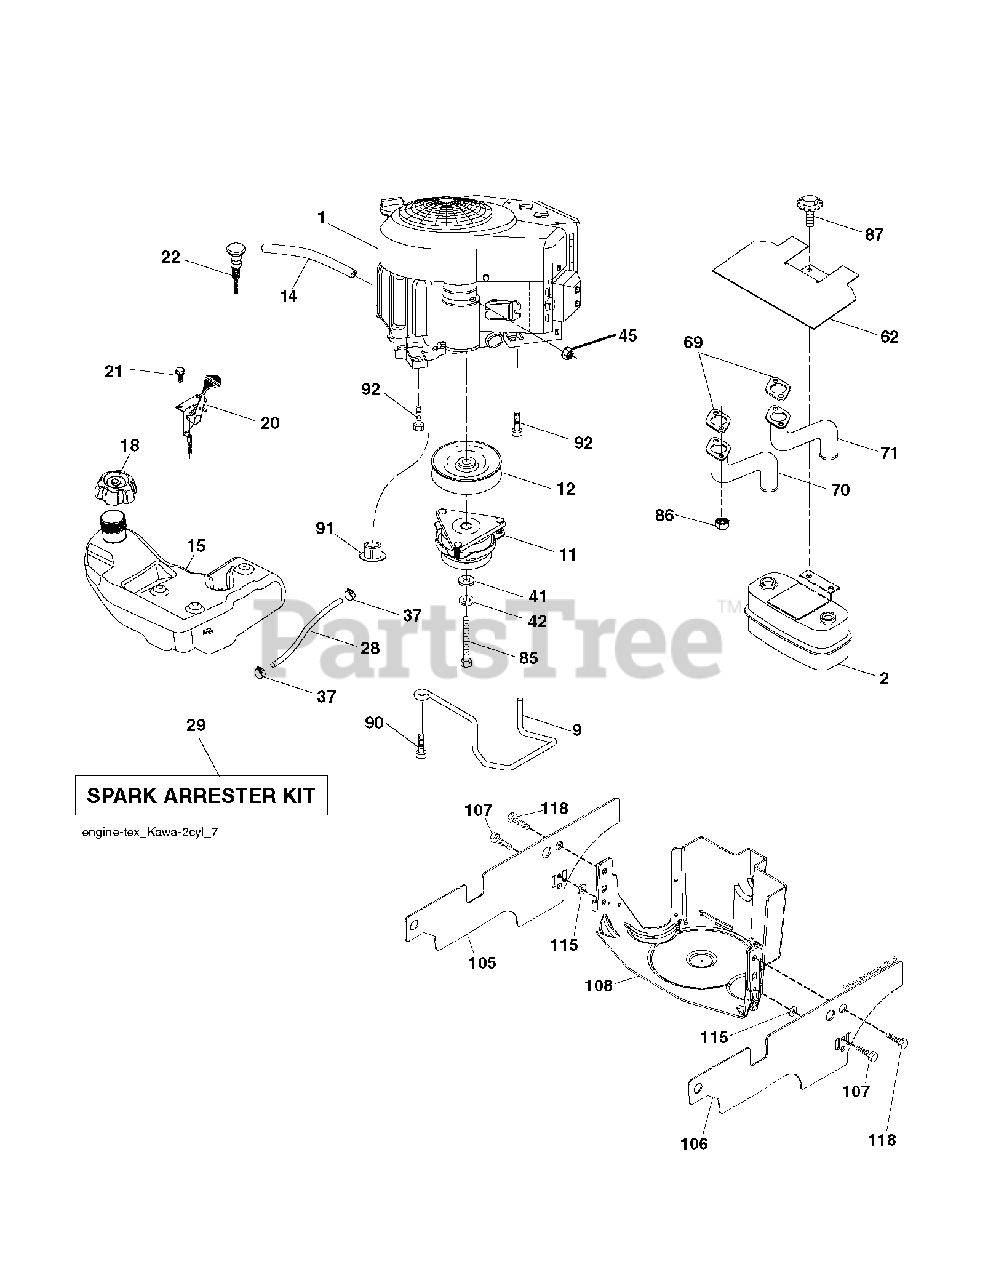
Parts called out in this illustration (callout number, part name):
1	Husqvarna TBD
2	MUFFLER.TWIN.CYL.LOW.TONE
9	KEEPER.BELT.ENGINE.4.2
11	CLUTCH.ELECTRIC.LT.48"*
12	PULLEY.ENGINE.TUFFTORQ
14	TUBE, DRAIN OIL ASM.
15	TANK.FUEL.4GAL
18	RP CAP FUEL
20	THROTTLE CABLE
21	SCREW.#10 X 0.750.BOS
22	CONTROL.CHOKE.ERGO.PUSH-IN.BLA
28	REPL BY 532 00 85-43
29	KIT.SPARK ARRESTOR 794945 B&S
37	HOSE CLAMP
42	LOCKWASHER
45	NUT
62	SHIELD.HEAT.MUFFLER
70	TUBE.EXHAUST.LH.FR961/FR730
71	TUBE.EXHAUST.RH.FR961/FR730
85	BOLT HEX 7/16-20X4-1/4"
86	NUT.HEX.FLANGE.TOPLOCK
87	Bolt, 5/16-18 X 1-3/4
90	SCREW 3/8-16X1
91	BUSHING.1.375OD
92	SCREW 3/8-16X1
105	SHIELD.SIDE.RH.3842"TEX FRENCH
106	SHIELD.SIDE.RH.46"FRENCH.TEX
107	SCREW.1/4-20X5/8
108	COVER
115	PALNUT 1/4
118	SCREW, 5/16-18 X 1/2
